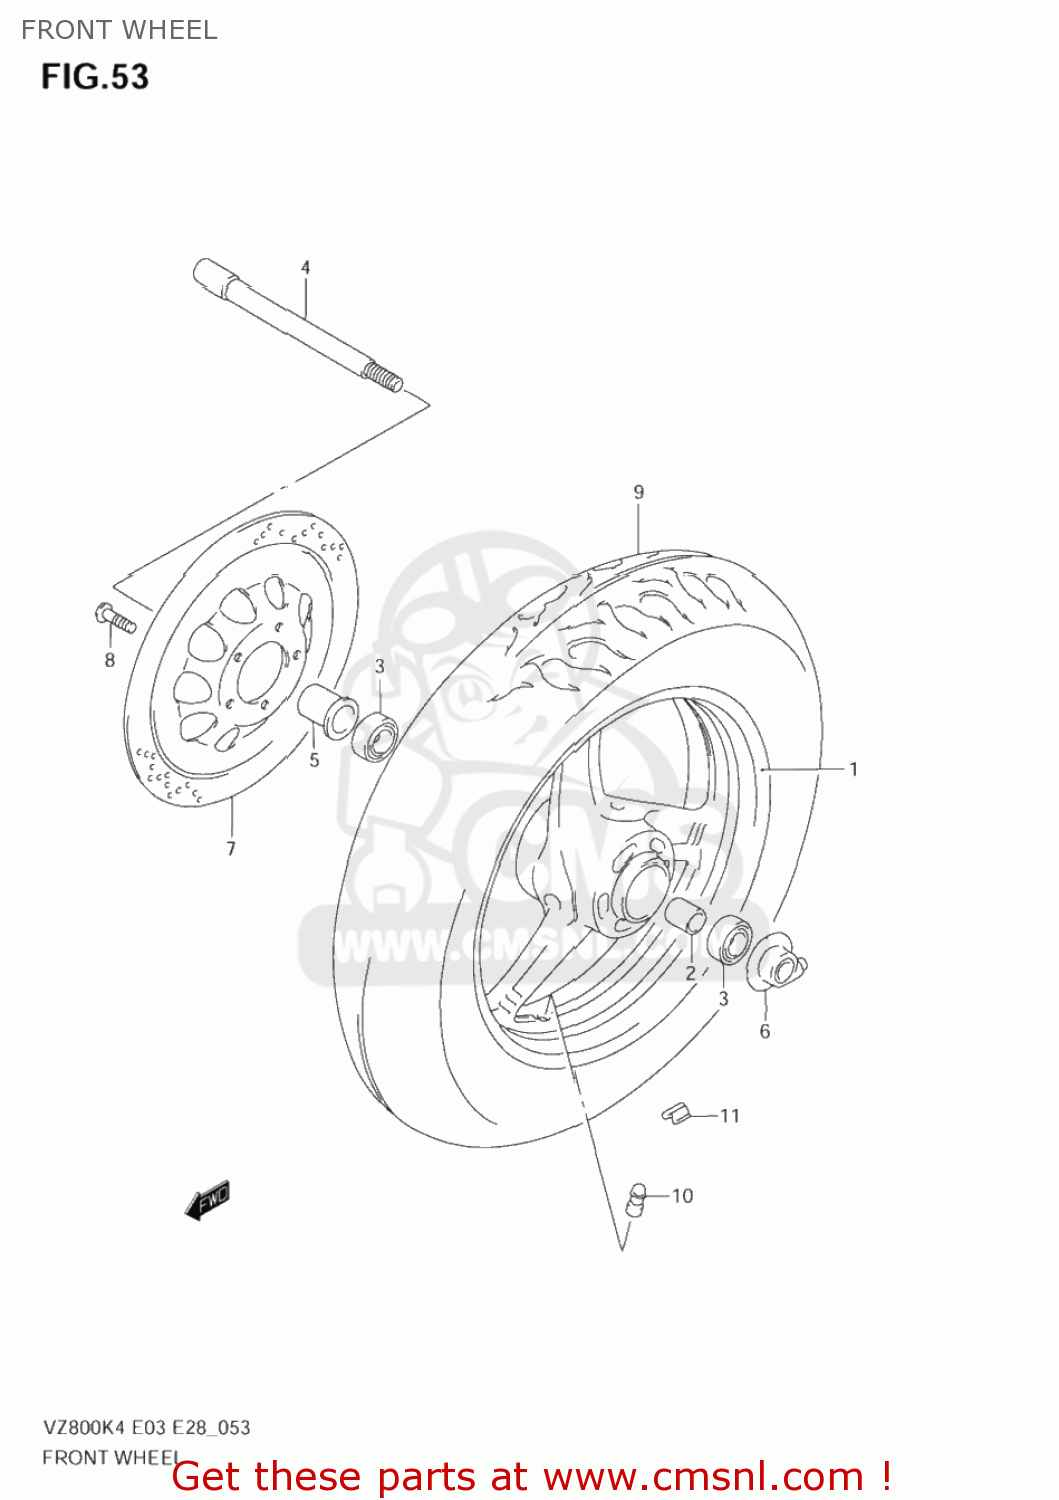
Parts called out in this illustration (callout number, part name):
1	WHEEL,FR(16XMT3.00)
2	SPACER(17.5X25X82.1)
3	BEARING
4	AXLE,FR
5	SPACER COMP,FRONT AXLE
6	BOX ASSY,SPEEDOMETER GEAR
7	DISC,FR BRAKE,R
8	BOLT 8X33
9	TIRE,FR(130/90-16 67H)
10	VALVE ASSY,WHEEL RIM(TR412)
11	BALANCER,WHEEL (10G)
